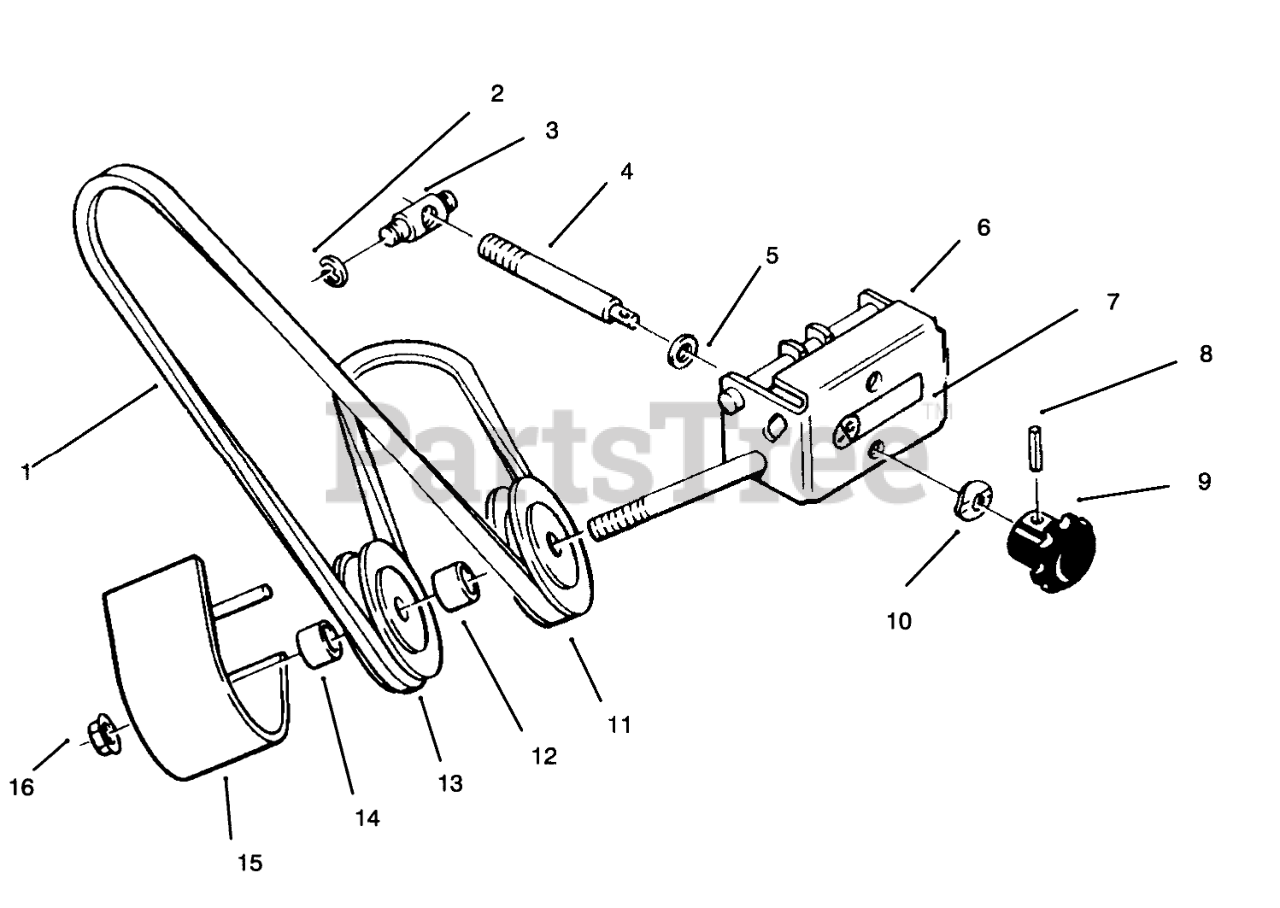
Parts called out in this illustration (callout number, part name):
1	V-BELT
2	RING-RETAINING
3	TRUNNION-DOUBLE
4	ROD ADJ
5	WASHER-FLAT
6	Front Support
7	Decal-Attac-O-Matic
8	PIN-ROLL
9	KNOB-ADJUSTMENT
10	WASHER-SPRING
11	Pulley-V
12	SPACER
13	PULLEY-FLAT IDLER
14	SPACER-OUTER
15	Belt Cover
16	Nut
